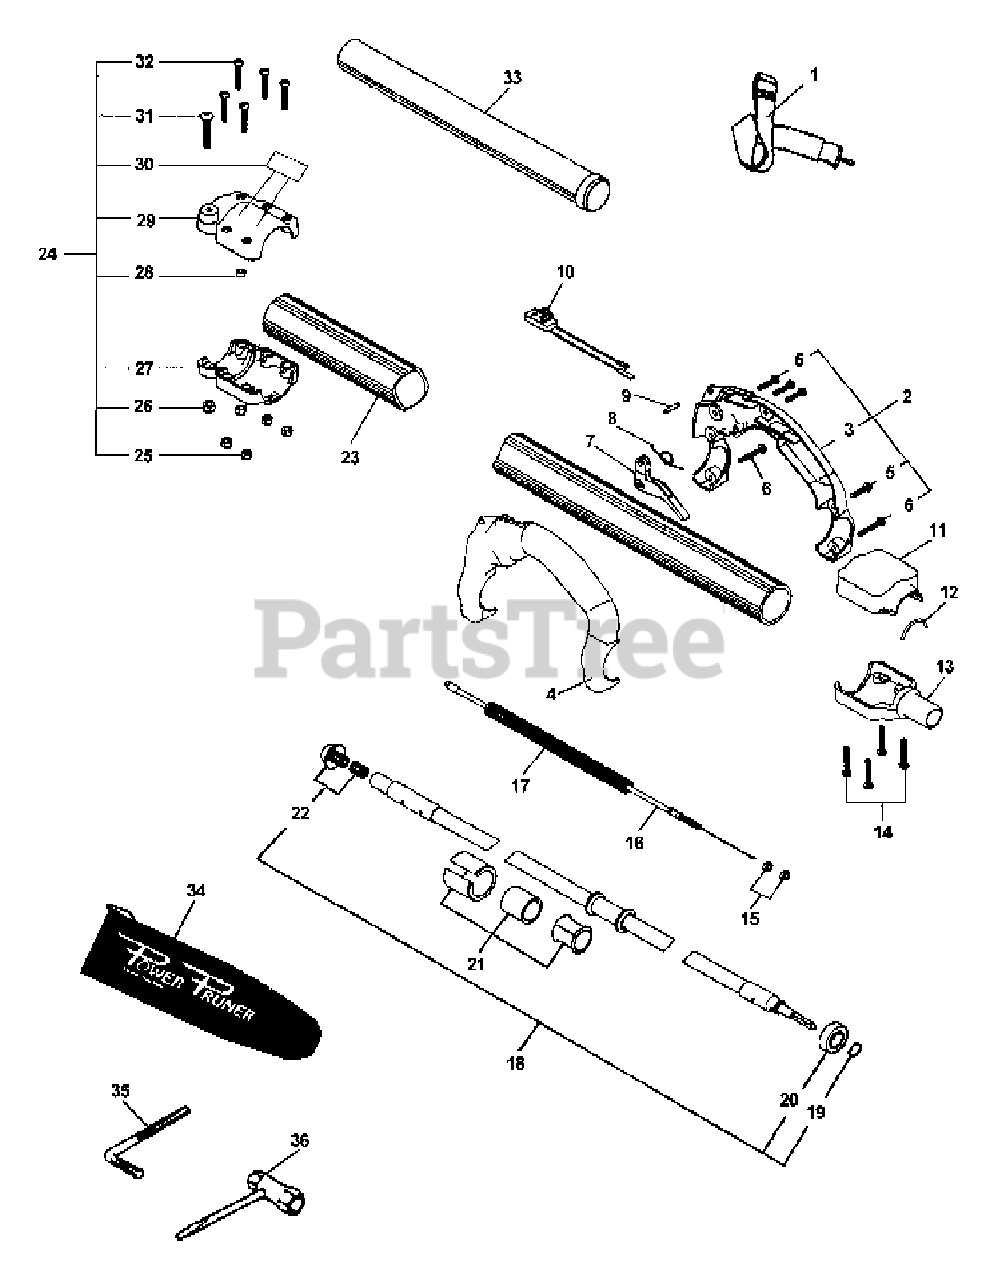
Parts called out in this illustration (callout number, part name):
1	SHOULDER STRAP ASSY
2	HANDLE ASSY - REAR
3	HANDLE, REAR - RIGHT
4	HANDLE, REAR - LEFT
5	SCREW - 10-24 X 1-1/4"
6	SCREW - 10-24 X 7/8"
7	TRIGGER, THROTTLE
8	SPRING, TRIGGER
9	PIN - LOCATING
10	IGNITION SWITCH ASSY
11	LOWER HSNG ADAPT (TOP)
13	ADAPTER - LOWER
14	SCREW - 10-24 X 1-1/4"
16	CABLE, THROTTLE
17	TUBE, PROTECTIVE - CORRUGATED
18	DRIVESHAFT ASSY
19	RING, RETAINING
20	BEARING, BALL - 6002
21	DRIVESHAFT GUIDE ASSY
22	ADAPTER, DRIVESHAFT - UPPER
23	PIPE, MAIN
24	COLLAR ASSY
25	LOCKNUT - 10-24
27	COLLAR, MAIN PIPE - LOWER
29	COLLAR, MAIN PIPE - UPPER
30	LABEL - CAUTION
32	SCREW - 10-24 X 1-1/4"
33	PIPE, MAIN
34	COVER, GUIDE BAR
35	HEX KEY - 3mm
36	T-WRENCH
